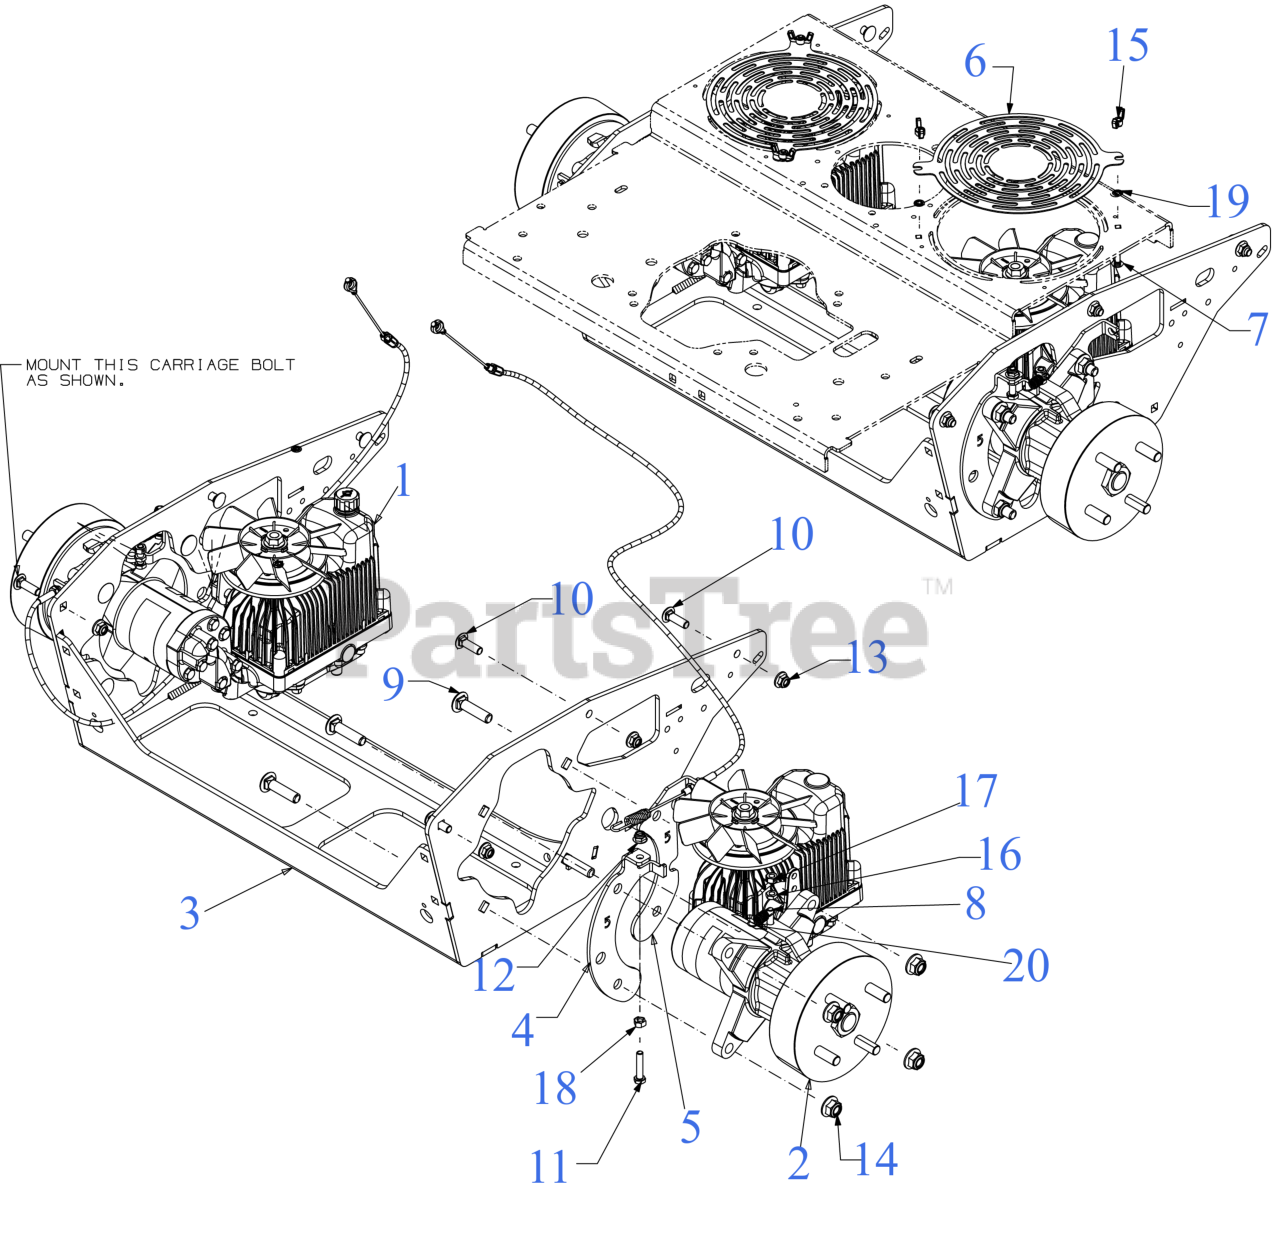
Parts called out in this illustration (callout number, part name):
1	TRANSMISSION / MOTOR ASSEMBLY (LH)
2	TRANSMISSION / MOTOR ASSEMBLY (RH)
3	TRANSMISSION MOUNTING BRACKET
6	TRANSMISSION COVER PLATE
7	CARRIAGE BOLT 1/4-20 x .62
8	SCREW 5/16-18 x 1.0 GR5
9	CARRIAGE BOLT 1/2-13 GR5
10	CARRIAGE BOLT 3/8-16 X1.25 GR5
11	SCREW 5/16-18 x 1.5 LG
12	FLANGE LOCK NUT 5/16-18
15	WING NUT 1/4-20
18	HEX NUT 5/16-18
19	RETAINER-BOLT .25ID x .50OD
20	EXTENSION SPRING .500 OD x 1.71
